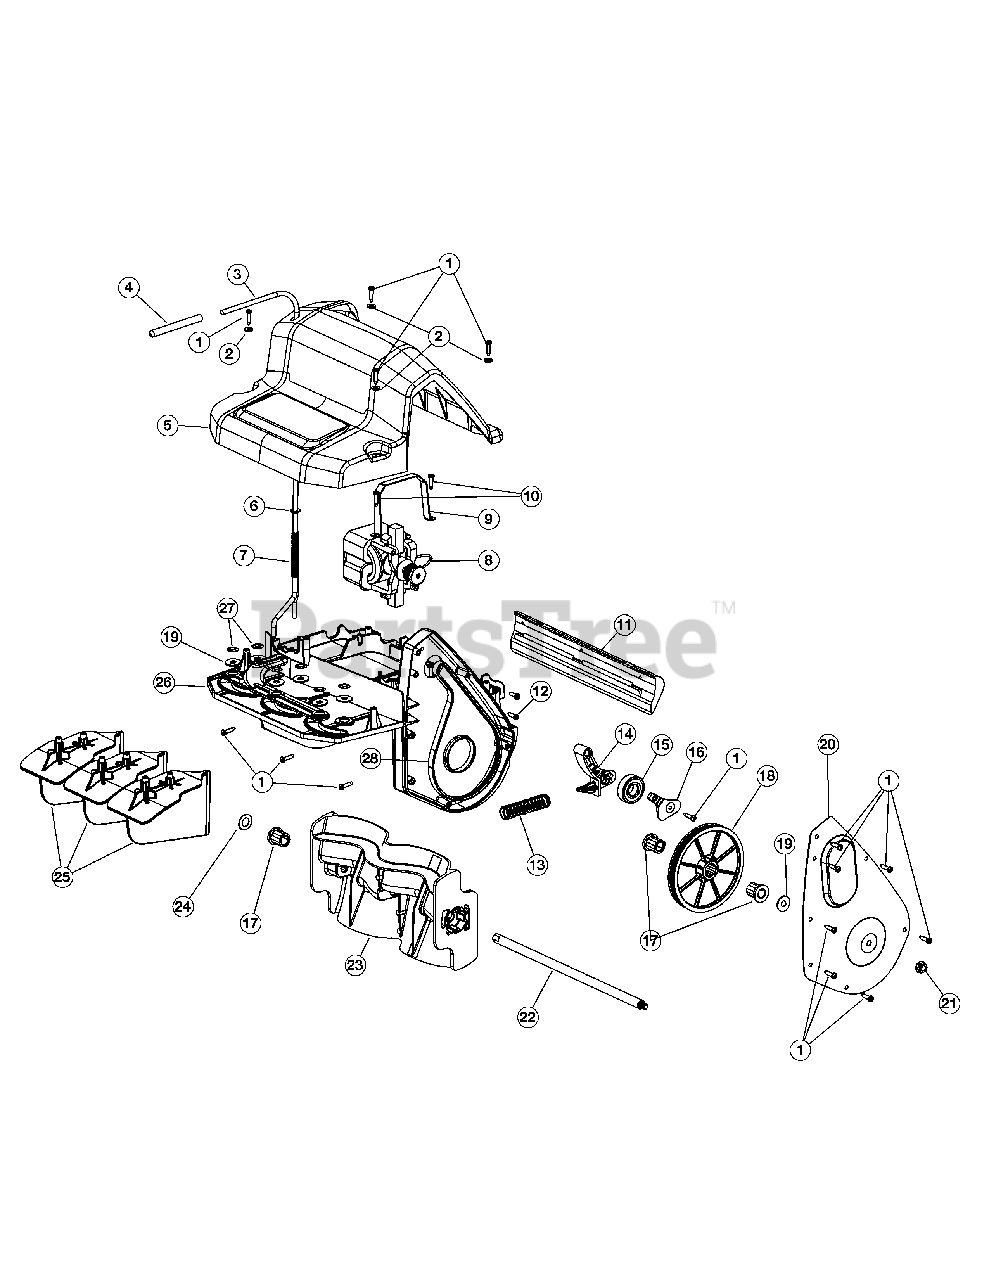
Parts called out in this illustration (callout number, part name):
3	Vane Control Handle
6	Washer
7	Spring
8	Motor Assm w/ Fan & Pulley
9	Motor Strap
10	Screw
11	Scraper
12	Screw
13	Spring
14	Idler Arm
15	Ball Bearing
16	Keeper
17	Flange Bearing
18	Driven Pulley
19	Washer
20	Bert Case Cover
21	Flange Lock Nut
22	Axle Auger
25	Vane
26	Snow Thrower Housing
27	Push Nut
28	Drive Belt
